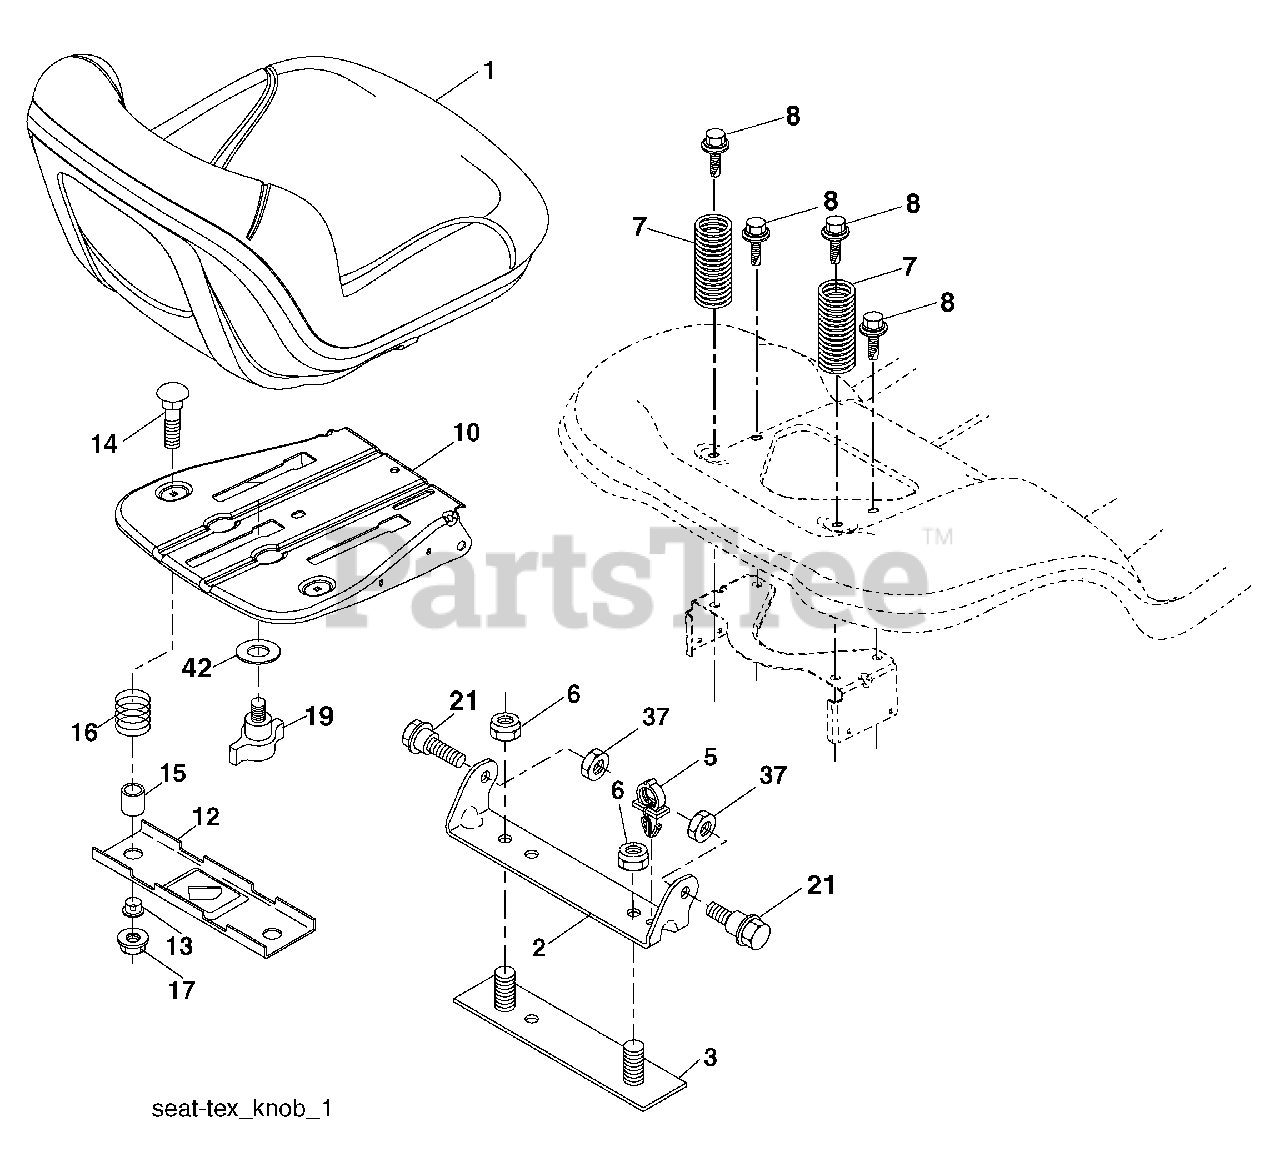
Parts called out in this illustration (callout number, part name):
1	Seat
2	Bracket Pivot Fender
3	Strap, Asm Fender
5	Clip Push-In Hinged
6	Nut, Lock w/Ins. 3/8-16 unc
7	Spring, Seat Cprsn
8	Bolt 5/16-18 unc x 3/4 w/Sems
12	Bracket Seat Mounting
13	Bushing Snap
14	Bolt 1/4 - 20 X 1-1/2
15	Spacer Split
16	Spring CPRSN Plate SW 1.310 Ga.
17	Nut Lock 1/4 Gr.5
19	Knob Seat
21	Bolt, Shoulder 5/16-18
37	Nut, Lock 5/16-18 unc
42	Washer Cup Seat
